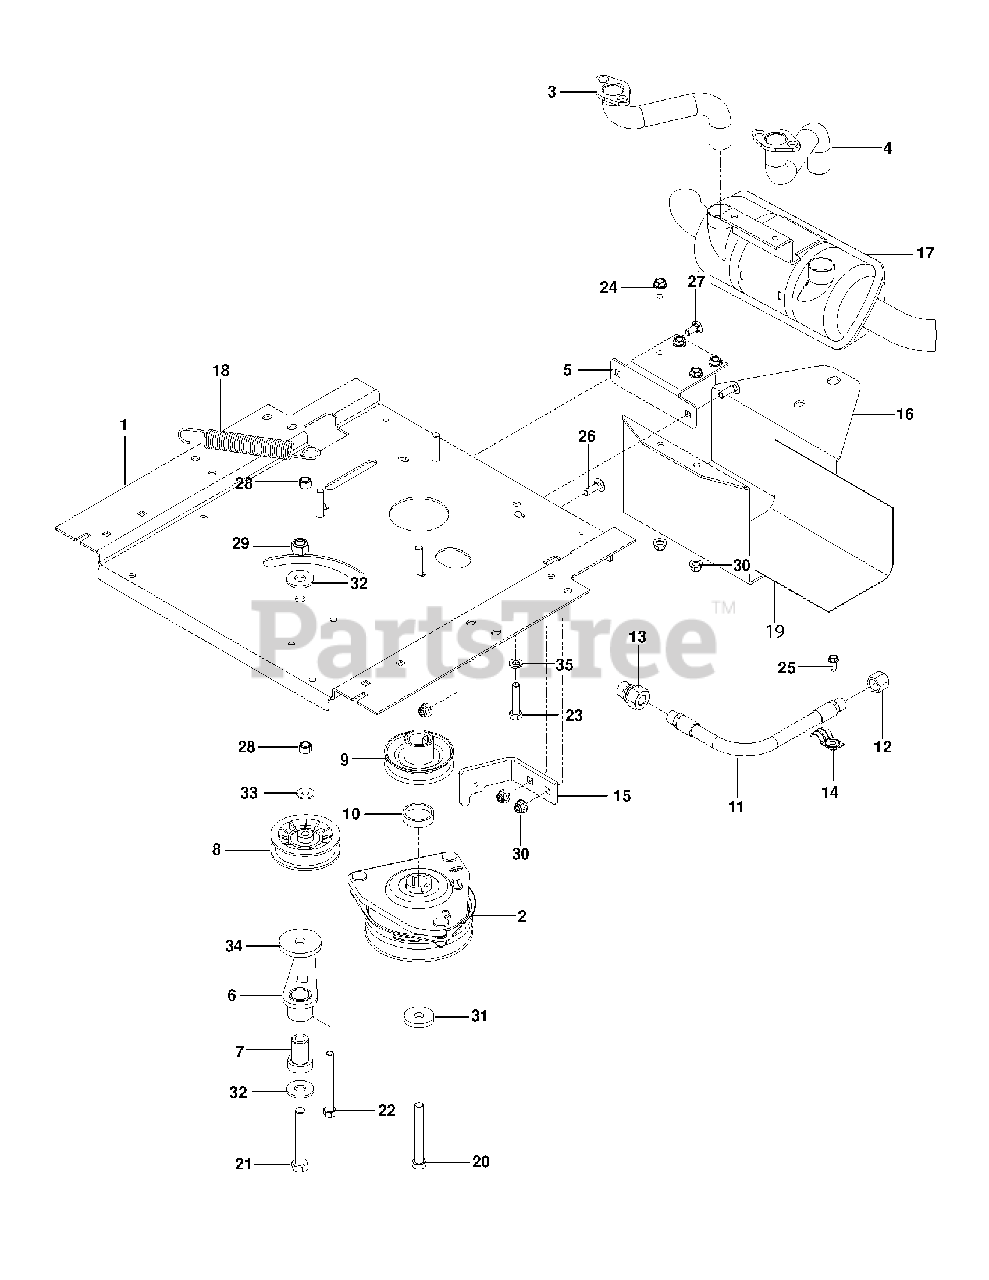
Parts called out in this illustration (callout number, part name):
5	BRACKET, MUFFLER, BLACK
7	IDLER SPINDLE
8	PULLEY, IDLER
9	PULLEY, ENGINE
10	SPACER, HUB PULLEY
11	OIL DRAIN HOSE
12	DRAIN CAP
13	ADAPTER, OIL DRAIN
15	CLUTCH STOP OGR BLK
16	GUARD, MUFFLER, BLACK
18	SPRING, DECK DRIVE
19	HEAT SHIELD
20	HCS 7/16-20 X 2.5 GR8
21	HCS 1/2C X 3 1/4
22	HCS 3/8-16X3 1/2 GR5
23	BOLT, HCS 3/8-16X1-3/4
24	BOLT 5/16-18 X 3/4
25	SCREW 1/4 X 5/8
26	RHSNB 5/16C X 1
27	BOLT 5/16C X 3/4" CARRIAGE
28	NUT 3/8-16 NYLOC
29	NUT 1/2-13 HEX NYLOC ZD
30	5/16-18 NYLOC FLANGE NUT
32	WASH USS FLAT 1/2
33	WASHER 5/16 FLAT
34	HEAVY WASHER
35	SLW 3/8 STD
